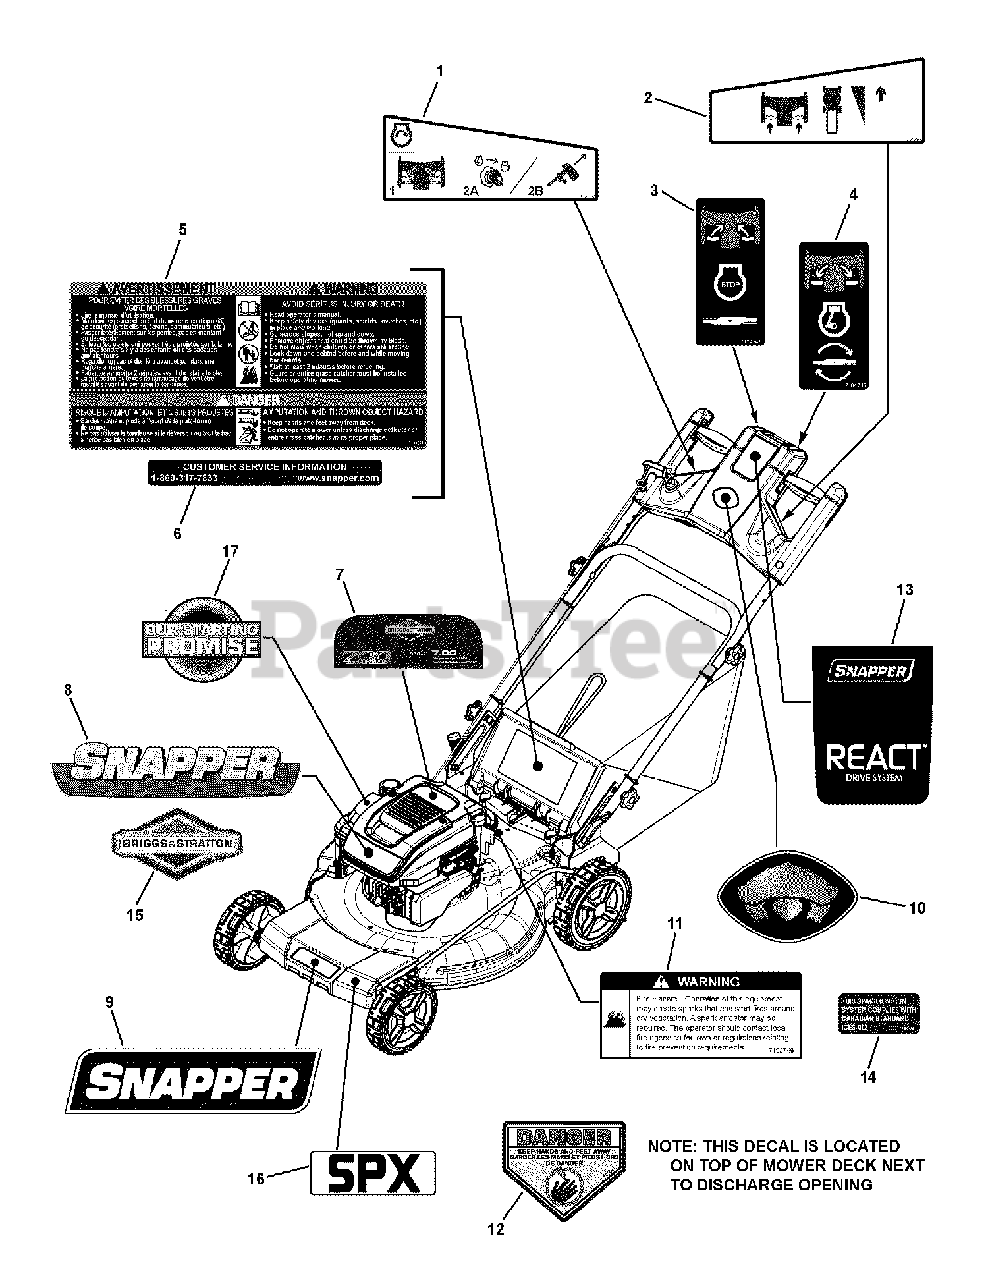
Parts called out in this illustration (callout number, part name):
1	DECAL, Start, React
2	DECAL, Drive, React
3	DECAL, Stop, React
4	DECAL, Run, React
5	DECAL, Walk-Behind Safety, French/English
6	DECAL, Customer Service, MY08, Snapper
7	DECAL, Briggs Engine, 700 Series
8	DECAL, Briggs Engine, Snapper
9	DECAL, Front Shroud, Snapper Logo
10	DECAL, Handle, Domed Turtle
11	DECAL, Spark Arrestor
12	DECAL, CPSC, French/English
13	DECAL, Handle React Drive
14	DECAL, Spark Compliance, ICES
15	* DECAL, B&S Logo
16	DECAL, B&S Front Cover "SPX" Series
17	DECAL, Starting Promise
